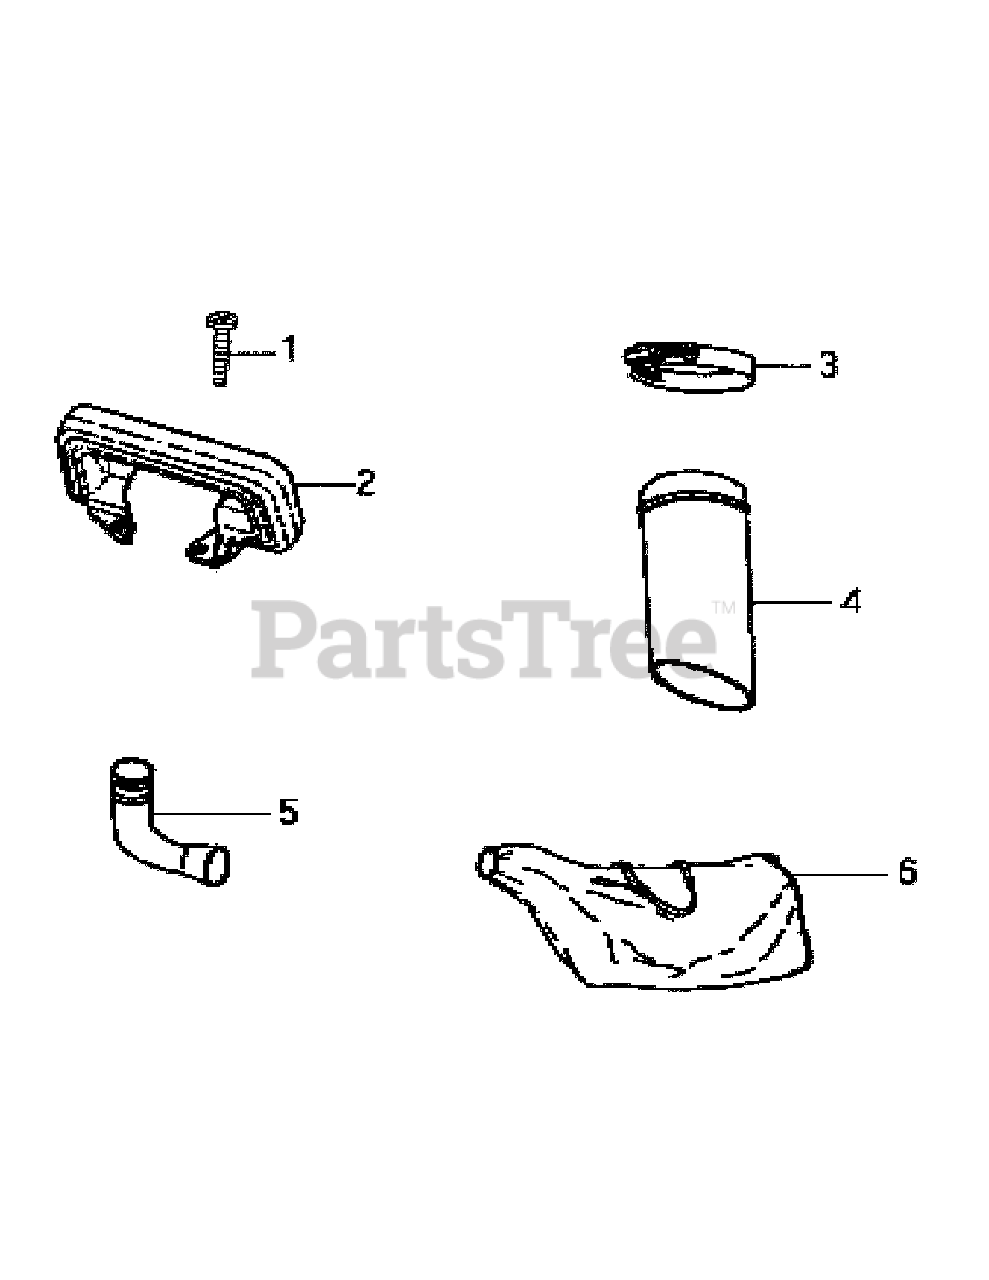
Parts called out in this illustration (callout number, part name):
2	Grip Complete
4	Pipe, Straight
5	Pipe, Curved
